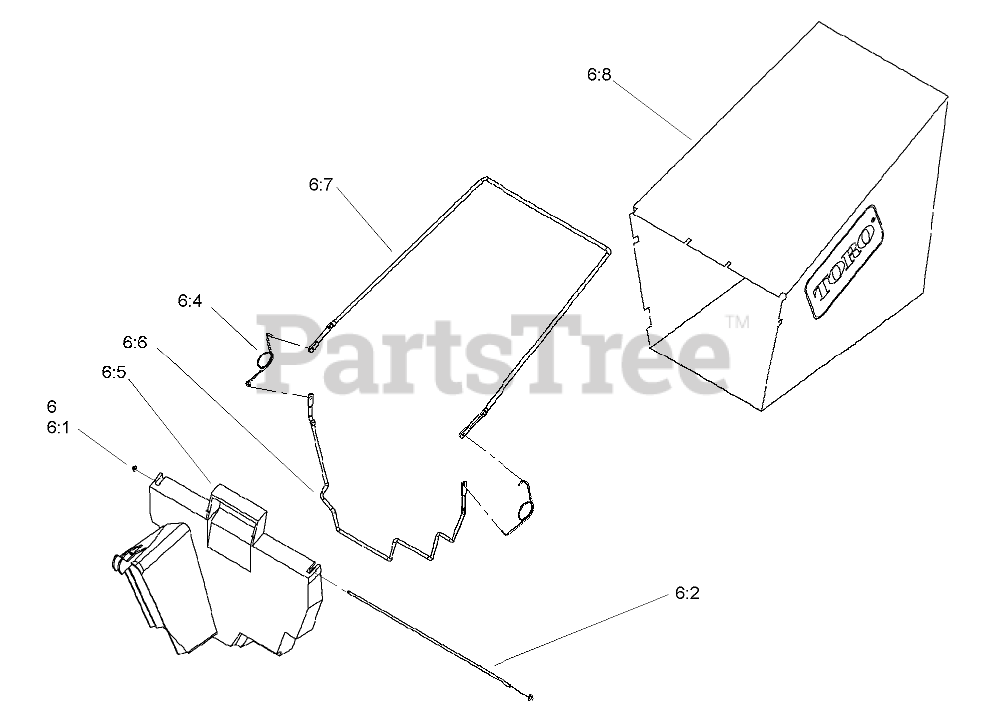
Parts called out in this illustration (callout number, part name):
6	GRASS BAG ASM
6:1	NUT-PUSH
6:2	HINGE-DOOR, BAG
6:4	SPRING
6:5	DOOR-BAG
6:6	FRAME-BAG
6:7	FRAME-BAG, UPPER
6:8	BAG-GRASS
